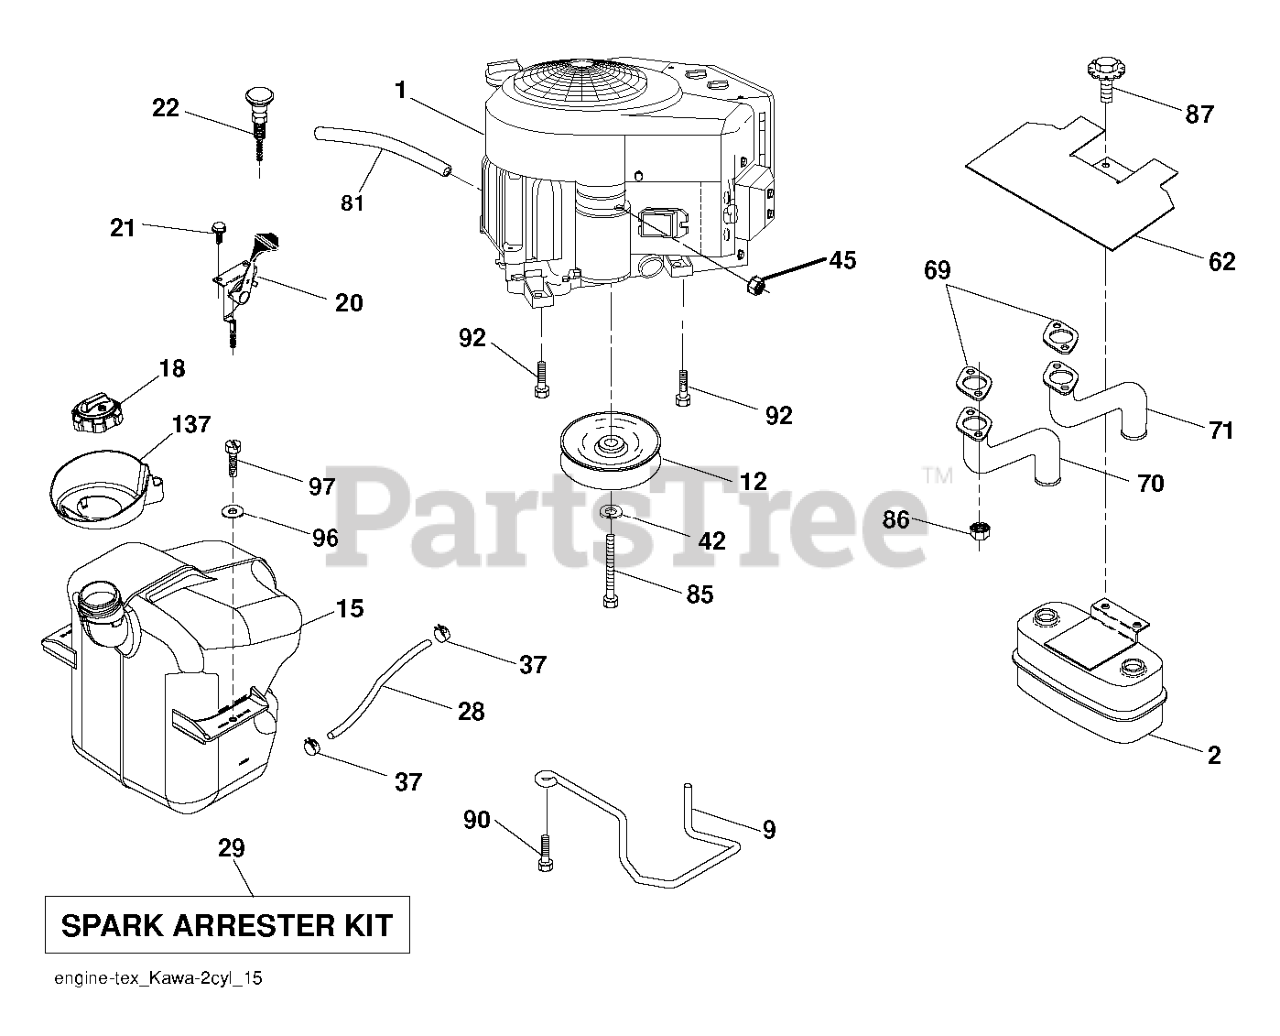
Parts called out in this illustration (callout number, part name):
2	MUFFLER.TWIN.CYL.LOW.TONE
9	KEEPER.BELT.ENGINE.4.2
12	PULLY ENGINE
15	FUEL TANK TANK. ASSEMBLY. EXTE
18	CAP.ASM.FUEL.2.25"TOP.TURN
20	THROTTLE CABLE
21	SCREW.#10 X 0.750.BOS
22	CONTROL.CHOKE.ERGO.PUSH-IN.BLA
28	LINE.FUEL.20
29	KIT.SPARK ARRESTOR 794945 B&S
37	HOSE CLAMP
42	LOCKWASHER
45	NUT
62	SHIELD.HEAT.MUFFLER
70	TUBE.EXHAUST.LH.FR961/FR730
71	TUBE.EXHAUST.RH.FR961/FR730
81	TUBE, DRAIN OIL ASM.
85	BOLT HEX 7/16-20X4-1/4"
86	NUT.HEX.FLANGE.TOPLOCK
87	BOLT 5/1618UNC X 3/4 W/ SEMS
90	SCREW 3/8-16X1
92	SCREW 3/8-16X1
96	WASHER
97	SCREW HEXWSHR 1/4-20X3/4
